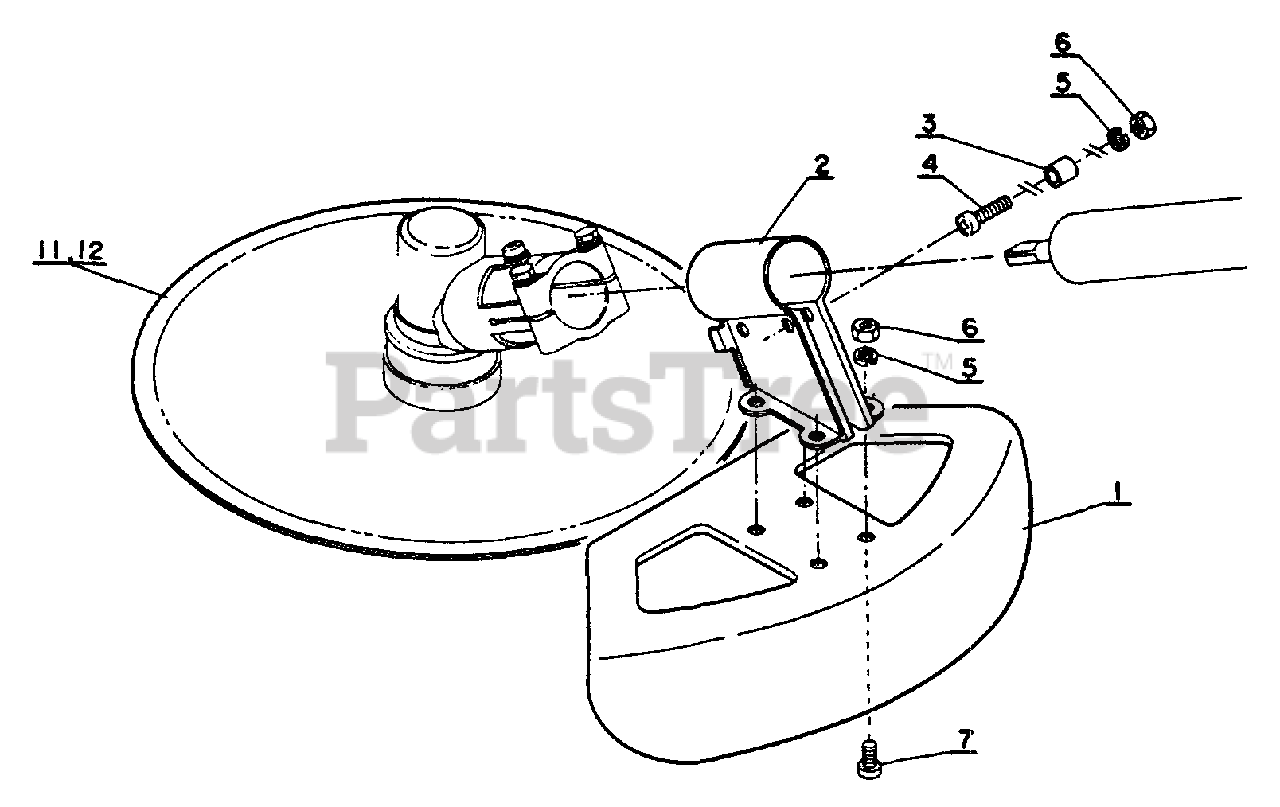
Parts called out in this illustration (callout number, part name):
2	SAFETY GUARD SET PLATE
3	SPACER, GUARD
4	SCREW 5×18
5	WASHER, SPRING 5
6	NUT M5
7	SCREW 5×8
11	SAW, CIRCULAR
12	BLADE - 8 TOOTH -- 10"
